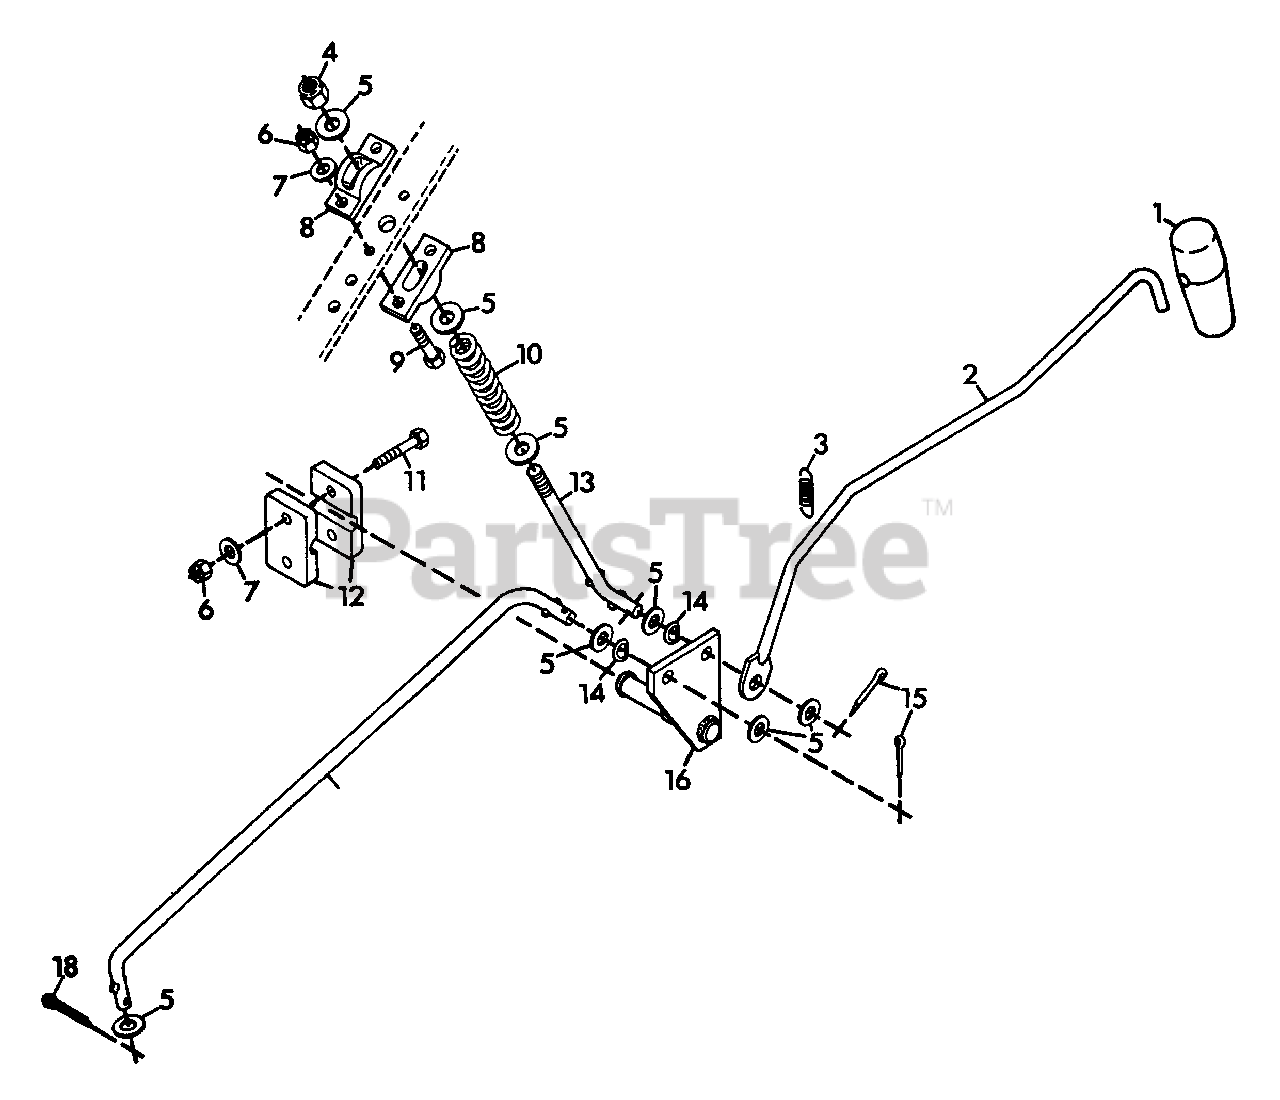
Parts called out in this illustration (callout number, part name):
1	Handle, Rubber Shifter
2	Rod, Shifter
3	Spring, Extension .50 x 1.25
4	Nut, Lock 3/8-16
5	Washer, Flat .406 x .812 x .065
6	Nut, Lock 1/4-20
7	Washer, Flat .281 x .625 x .065
8	Cam, Shifter
9	Bolt, Hex 1/4-20 x 1.00
10	Spring, Compression .720 x 2.75
11	Bolt, Hex 1/4-20 x 1.50
12	Block, Shift Lever
13	Link, Shifter Stop
14	Washer, Spring .375 I.D.
15	Pin, Cotter .125 x .750
16	Weldment, PTO Bellcrank
17	Link, PTO Control
18	Pin, Cotter .09 x .75
